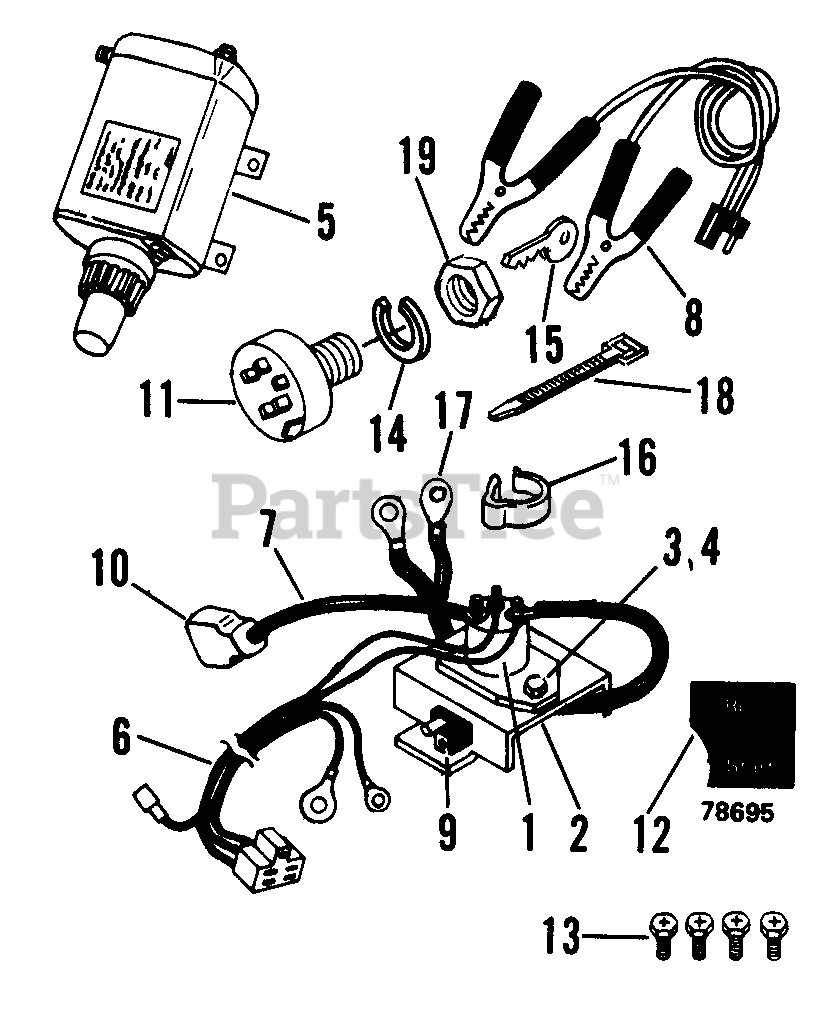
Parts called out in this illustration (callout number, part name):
1	BRACKET
2	SOLENOID
3	BLT-HEX .25-20X.50 PL GR2
4	NUT-LK-CTR .250-20 PL
6	WIRING HARNESS
8	JUMPER CABLE W/CONNECTOR
9	ADAPTER LEAD W/CONNECTOR
10	INSULATOR
11	IGNITION SWITCH ASSEMBLY
12	DECAL-SWITCH
13	SCR-CAP CR SEMS .25-20X.50 PL
14	WSHR-LK-INT .625X.045 PL
15	KEYS
16	CONDUIT CLAMP 2 WIRE
17	GROUND WIRE
18	TIE DOWN
19	NUT .625-32 ALUM
